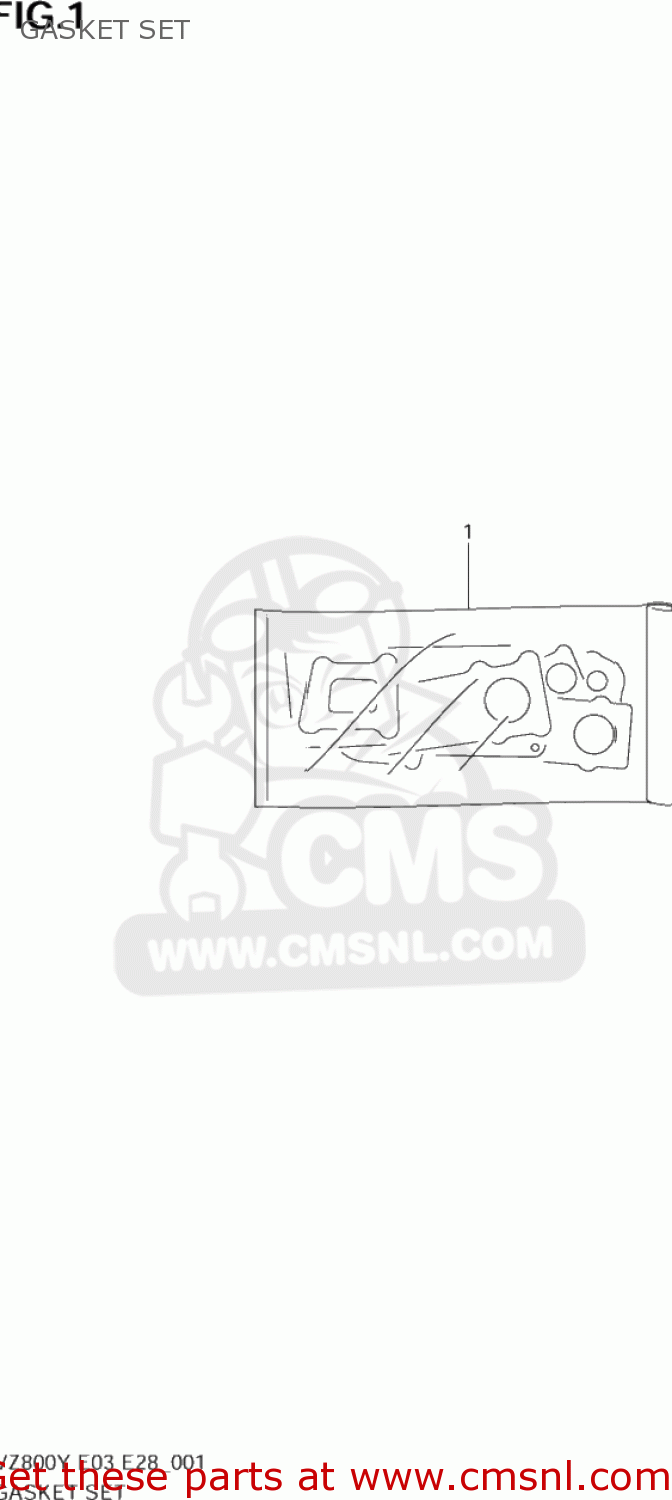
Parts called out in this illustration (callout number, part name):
1	GASKET SET (NAS)
2	GASKET,CYLINDER HEAD WATER (NAS)
3	GASKET,CYLINDER HEAD FR (NAS)
4	GASKET,CYLINDER HEAD RR (NAS)
5	GASKET,INSPECTION CAP (NAS)
6	GASKET,WATER OUTLET UNION (NAS)
7	GASKET,BREATHER COVER (NAS)
8	GASKET,CYLINDER (NAS)
9	O RING,OUTLET WATER CHAMBER
10	O RING,INLET WATER CHAMBER
11	GASKET,CLUTCH COVER
12	GASKET,CLUTCH COVER
13	GASKET,EXHAUST PIPE (NAS)
14	O-RING (D:2.4 ID:39.7)
